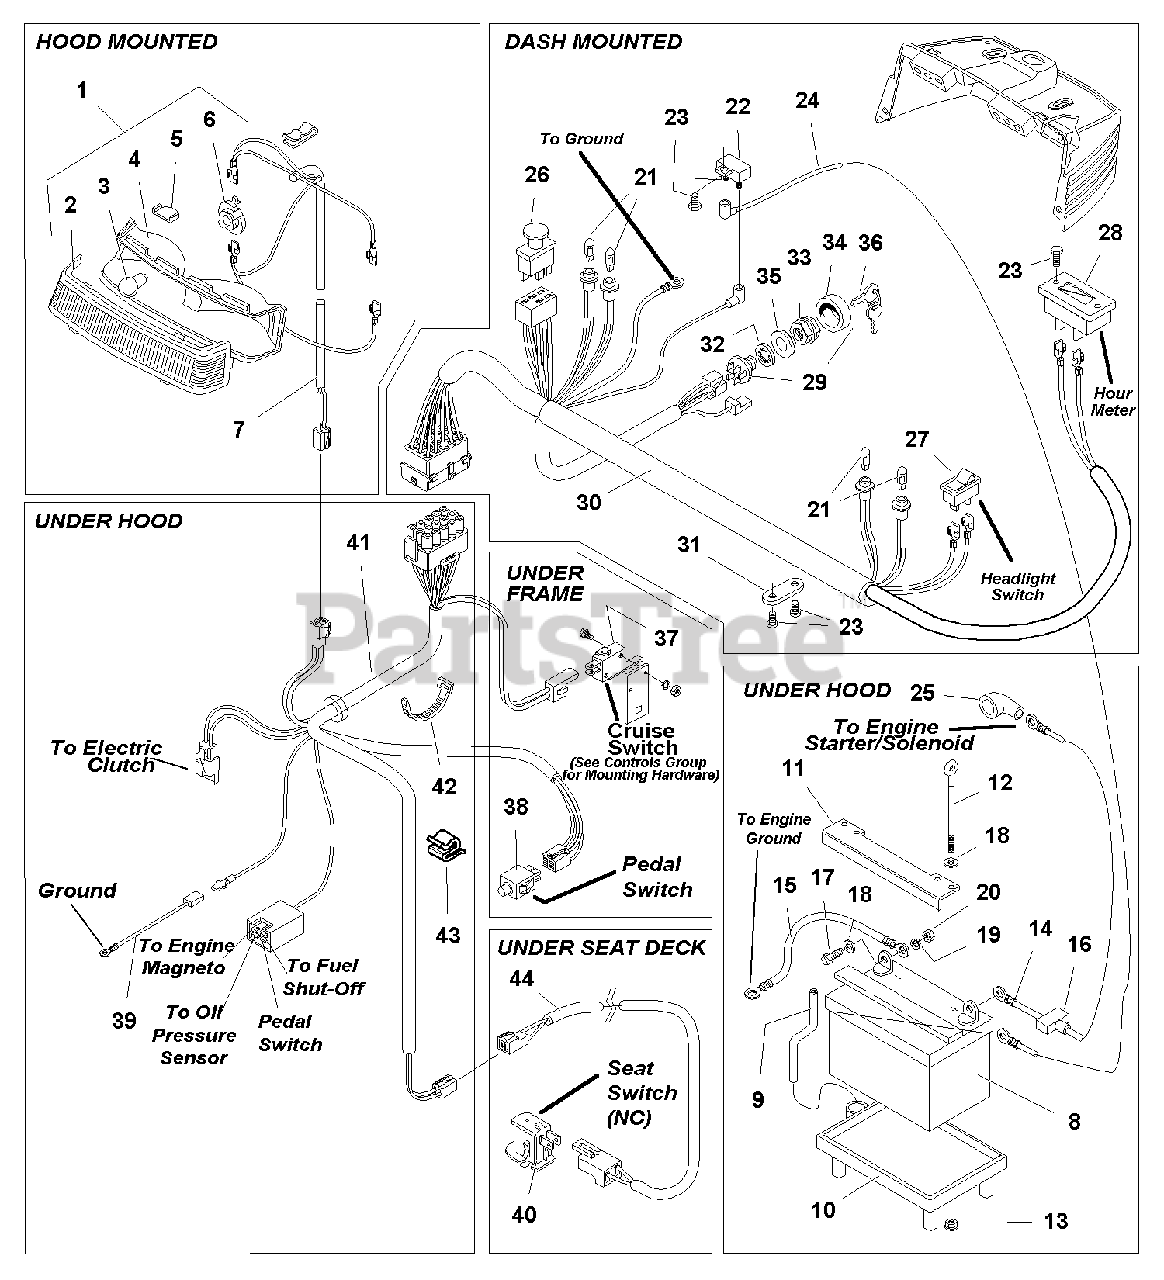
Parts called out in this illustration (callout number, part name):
1	HEADLIGHT ASSEMBLY, Complete (Includes Ref. Nos. 2-6)
2	LENS, Headlight
3	BULB, Headlight
4	BEZEL, Headlight
5	HEAT SHIELD
6	SOCKET, Bulb
7	WIRE ASSEMBLY, Headlight
8	BATTERY KIT
9	HOSE, Battery, Drain
10	TRAY, Battery
11	HOLD DOWN, Battery
12	ROD, Battery Hold Down
13	NUT, Plastic, 1/4-20
14	CABLE, Battery to Solenoid
15	CABLE, Battery to Ground
16	BOOT, Insulator
17	CAPSCREW, Hex Head, 1/4-20 x 3/4
18	WASHER, 1/4
19	WASHER, Lock, 1/4
20	NUT, Hex, 1/4-20
21	BULB, Indicator Light
22	CIRCUIT BREAKER
23	CAPSCREW, Hex Head, Plastite, #8-16 x 1/2
24	WIRE ASSEMBLY
25	COVER, Terminal
26	SWITCH, PTO Electric Clutch
27	SWITCH, Headlight
29	SWITCH ASSEMBLY, Ignition (Includes Ref. Nos. 39, 40, 41, 47 & 48)
30	WIRING HARNESS, Upper
31	STRAP, Wire Retainer
32	WASHER, Lock, Internal Tooth
33	NUT, Hex Flange, 5/8
34	COVER, Key Switch
35	WASHER, 5/8
36	KEYS, Set of 2
37	SWITCH, Interlock
38	SWITCH, Pedal
39	WIRE ASSEMBLY, Engine Ground
40	SWITCH, Seat (NC)
41	WIRING HARNESS, Lower
43	CLIP, Wire
44	WIRE ASSEMBLY, Seat Switch
